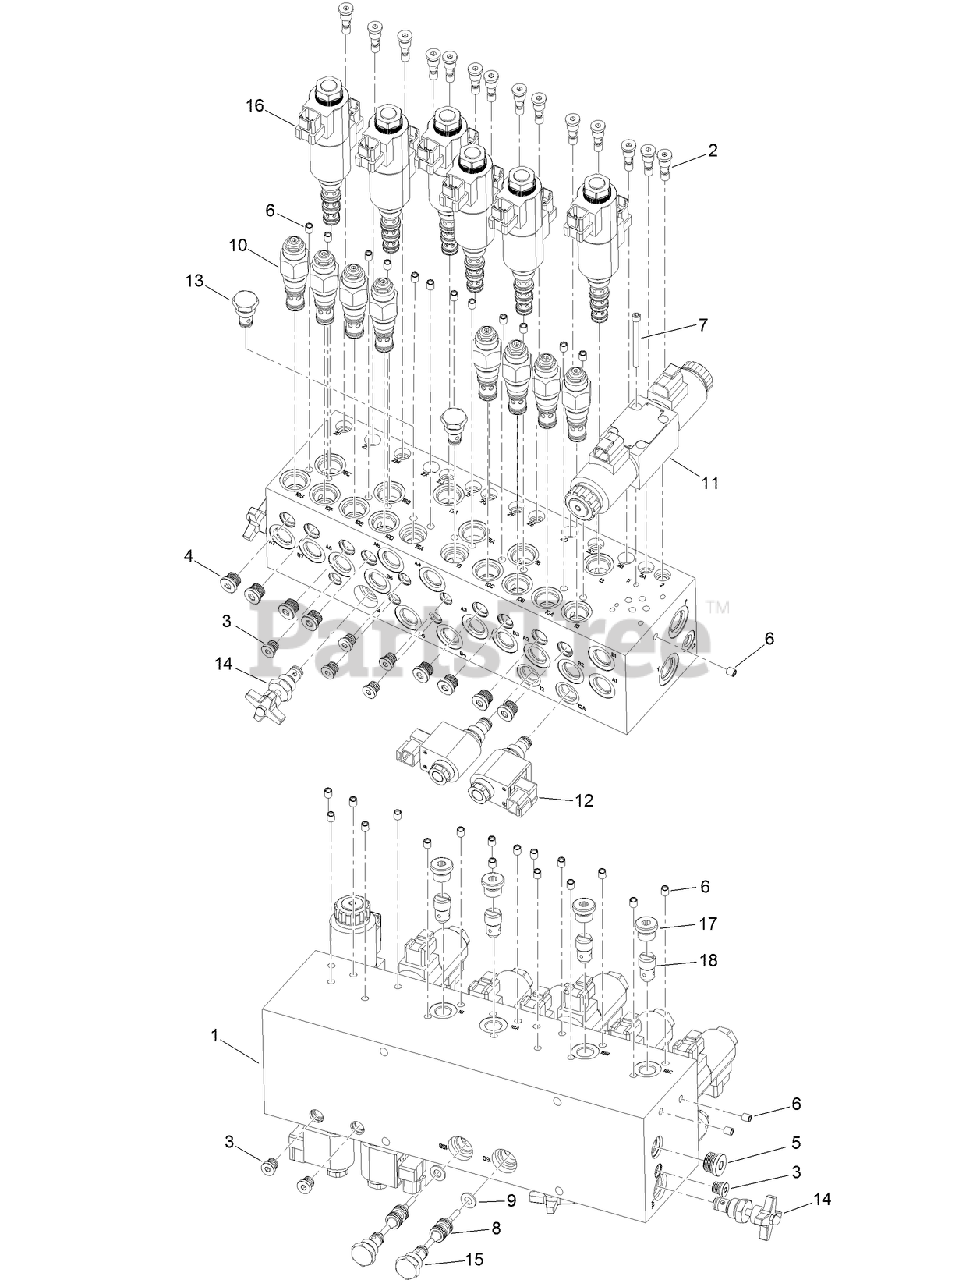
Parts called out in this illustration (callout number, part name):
1	BLOCK-MANIFOLD
2	VALVE-CHECK
6	PLUG-EXPANSION
7	SCREW-SHCS
8	PISTON
9	RING-BACKUP
10	VALVE-COUNTERBALANCE
11	VALVE-PROPORTIONAL
12	VALVE-SOLENOID
13	CARTRIDGE-HYDRAULICS, AUXILIARY
14	VALVE-NEEDLE
15	VALVE-CHECK
16	VALVE-SOLENOID
18	VALVE-FLOW CONTROL, PRESSURE COMPENSATED
